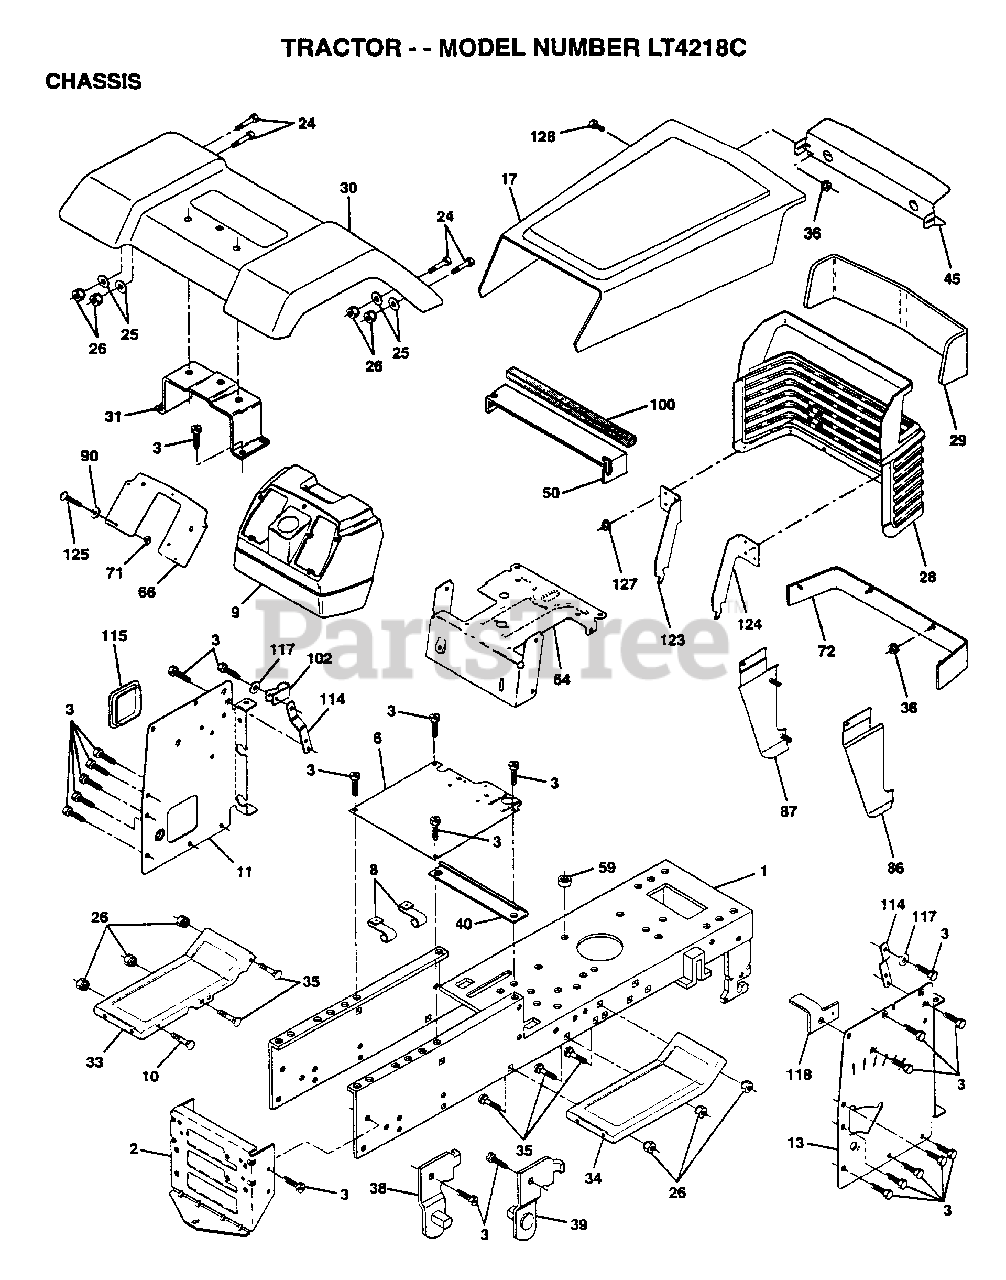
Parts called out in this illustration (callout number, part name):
1	CHASSIS.WLD.11GA
3	SCREW
8	"CLIP,INSULATOR"
9	DASH.PLASTIC.BLK
11	PANEL.DASH.LH.
13	PANEL.DASH.RH.NOT
16	NUT
17	HOOD/GRILLE ASM
20	PLATE.SUPT.BATTER
24	BOLT
25	WASHER
26	NUT.LK.W/WSH.1/2.
28	GRILLE ASM WELD
31	BRACKET SUPT FEND
33	FOOTREST.LH.LT/GT
34	FOOTREST.RH.LT/GT
35	BOLT
36	PAL NUT LT
38	BRACKET ASM LH
39	BRACKET ASM RH
40	SPACER FENDER LT
41	PLATE EXTEN FEND
50	"BAFFLE,HOOD"
60	BOLT
61	WASHER
66	PLATE DASH SILKSC
71	NUT HXKEP 1/4X20
72	STRAP FENDER ASM
86	PANEL SIDE RH ASM
87	PANEL SIDE LH ASM
90	WASHER PM
100	FOAM STRIP T
102	CLIP T
114	BRACKET.SUPT.DASH
115	COVER ACCESS
117	WASHER.SERRATED.
118	BRACKET.CLUTCH.MC
124	BRACKET.PICK.RH
125	SCREW
127	PAL NUT
128	SCREW SPECIAL
